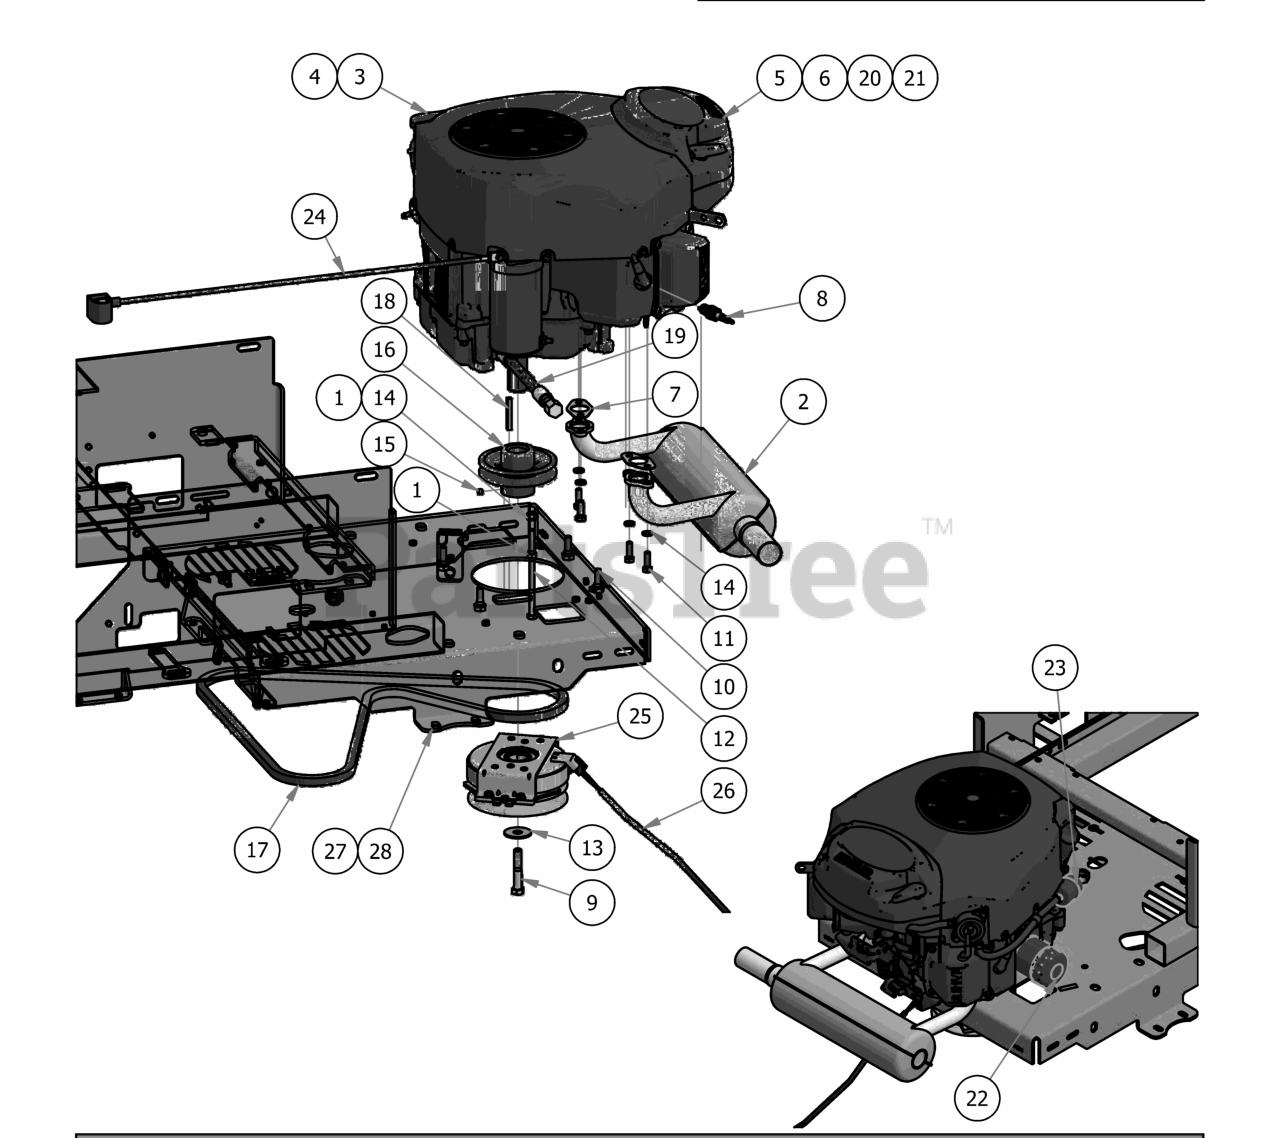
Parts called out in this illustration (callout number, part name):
2	Kohler Muffler
3	Kohler KT740 Engine
4	Kohler KT745 Engine
5	Kohler KT745 Air Pre-Cleaner
6	Kohler KT745 Air Filter Element
7	Exhaust Gasket
8	Spark Plug
9	7/16"-20 x 2.5" Hex Bolt Gr. 8
10	3/8 x 1 1/8 bolt
11	5/16" x 1" Bolt
12	5/16-18 x 5-1/2 GR 5 Hex Bolt
13	1/2" Belleville Washer
14	5/16" Lock Washer
15	5/16 Set Screw
16	4 3/4 Motor Pulley
18	1/4 x 2 Square key Stock
19	Oil drain Hose
20	Kohler KT740 Precleaner
21	Kohler KT740 Air Element
22	725 & 747 Kohler Oil Filter
23	Universal Inline Fuel Filter
24	24" Black Ground Cable
26	Clutch Pigtail
27	2017 MZ/ZT 54"-60" Frame
28	2017 MZ/ZT 42"-48" Frame
